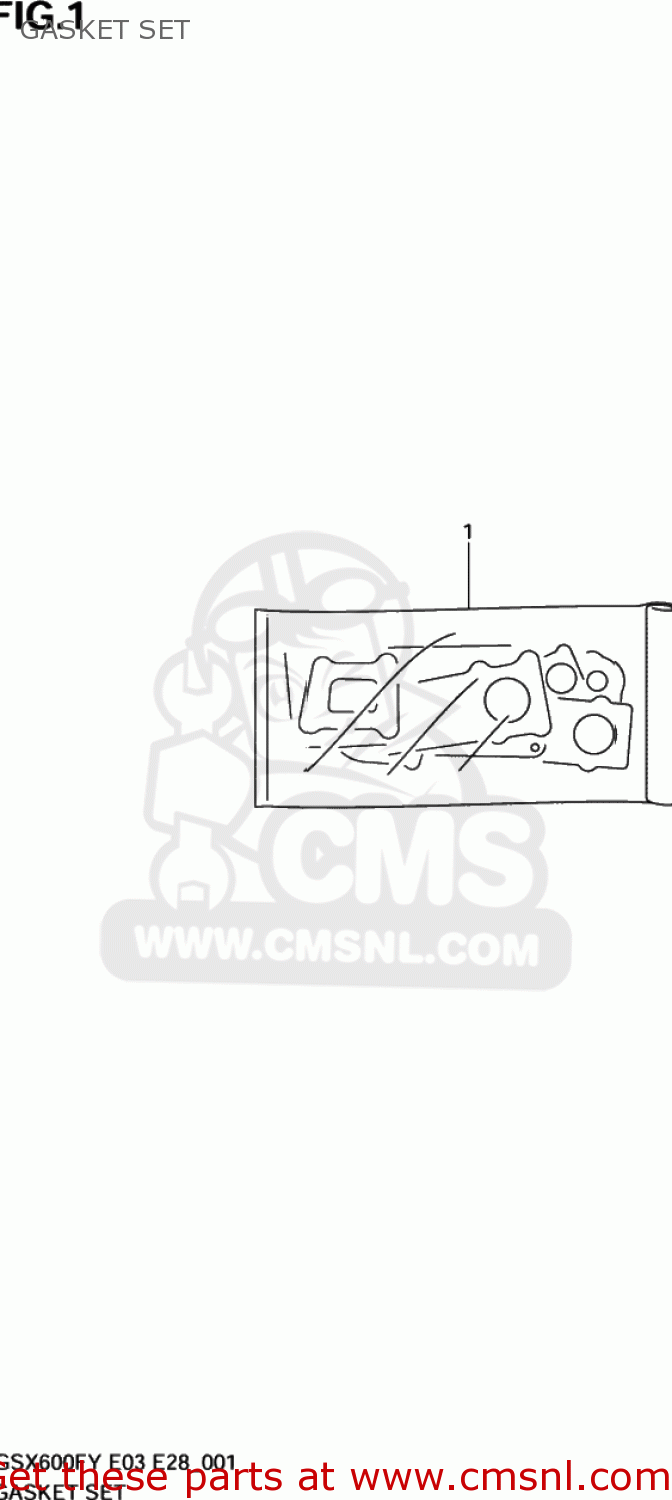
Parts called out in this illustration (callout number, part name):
1	GASKET SET (NAS)
2	GASKET,CYLINDER HEAD (NAS)
3	GASKET,CYLINDER HEAD COVER (NAS)
4	GASKET,BREATHER COVER (NAS)
5	GASKET,HEAD COVER NO.2 (NAS)
6	GASKET,HEAD COVER NO.3 (NAS)
7	GASKET,CYLINDER (NAS)
8	GASKET,CL COVER (NAS)
9	GASKET,STARTER GEAR COVER (NAS)
10	GASKET,OIL PAN (NAS)
11	GASKET,SIGNAL GEN COVER (NAS)
12	GASKET,TENSIONER ADJUSTER (NAS)
13	GASKET,EXHAUST (NAS)
14	O RING,OIL PUMP
15	GASKET,OIL STRAINER PROTECTOR (NAS)
16	GASKET,OIL OUTLET (NAS)
17	WASHER(10.6X25.5X2.3)
18	GASKET(5.8X11X1.2) (NAS)
19	GASKET 8.2X14X1 (NAS)
20	GASKET(8.5X17X2.3) (NAS)
21	GASKET(10.2X20X2).3 (NAS)
22	GASKET(14X19.2X2) (NAS)
23	GASKET(16X22X2) (NAS)
24	GASKET(16X22X2) (NAS)
25	O RING(D:1.2,ID:4)
26	O RING(D:2.6,ID:12.1)
27	O RING(D:2.5,ID:13.8)
28	O RING(D:2.4,ID:16.8)
29	O RING(D:3.1,ID:16.8)
30	O RING(D:3.2,ID:17.8)
31	O RING(D:2.5,ID:21)
32	O RING(D:3.7,ID:21.7)
33	O RING(D:3,ID:24.5)
34	O RING(D:2.4,ID:36.5)
35	O RING(D:2.4,ID:39.7)
